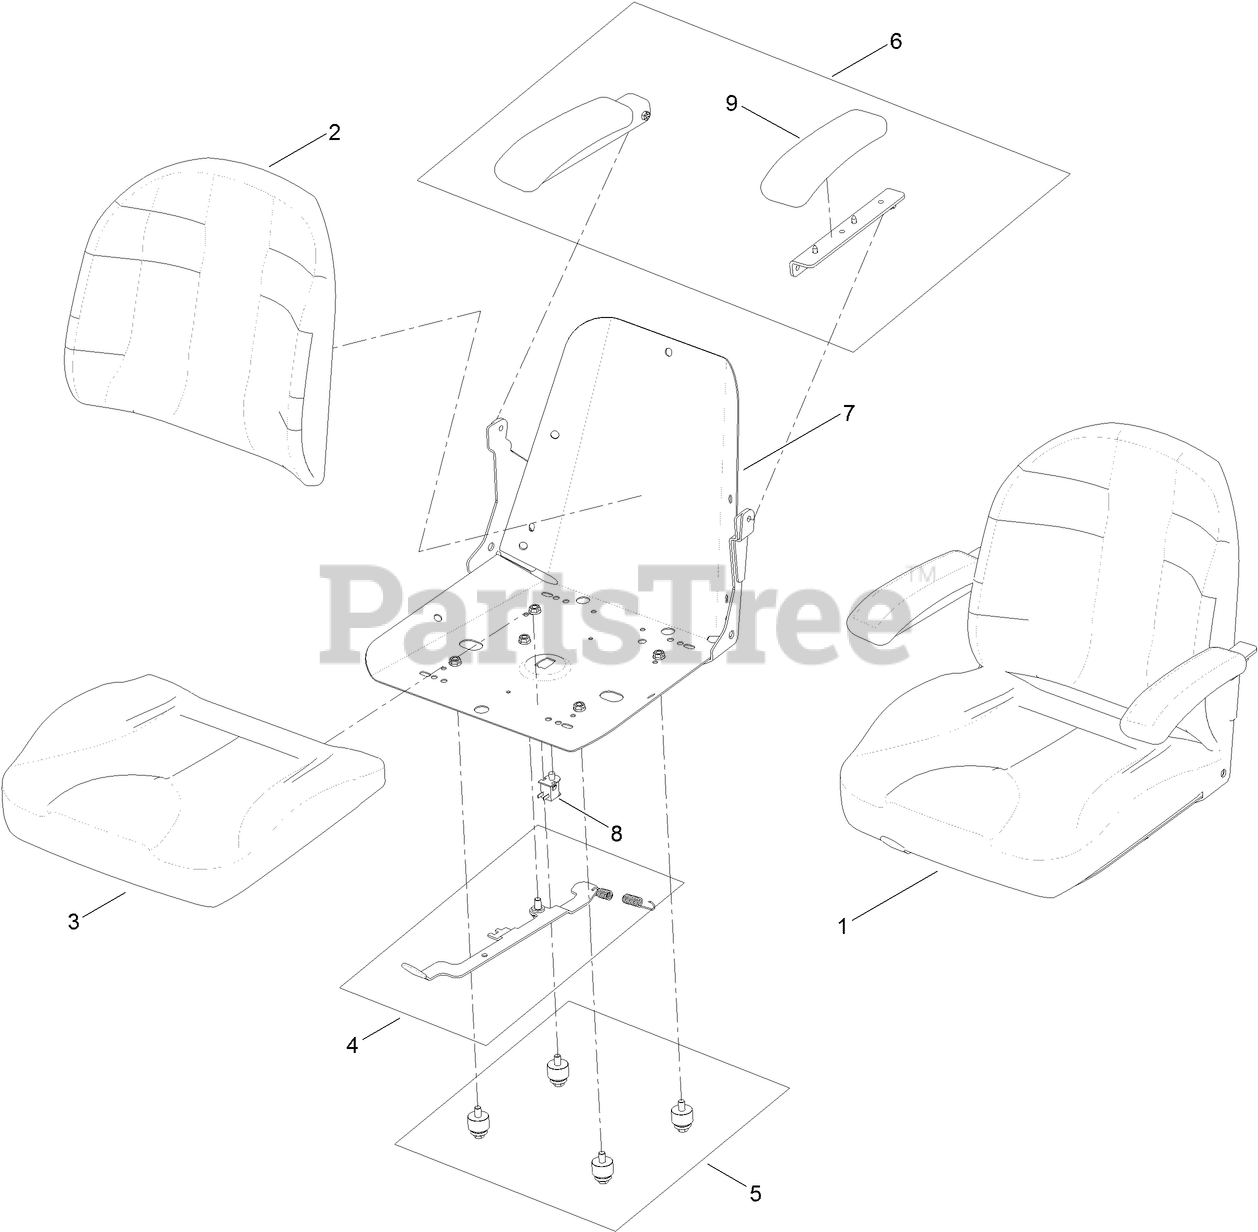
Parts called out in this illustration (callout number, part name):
1	SEAT ASM
2	CUSHION-SEAT, BACK
3	CUSHION-SEAT, BOTTOM
4	TRACK ASM
5	BUSHING ASM
6	ARMREST KIT
8	SWITCH-BAIL
9	CUSHION-REST, ARM
